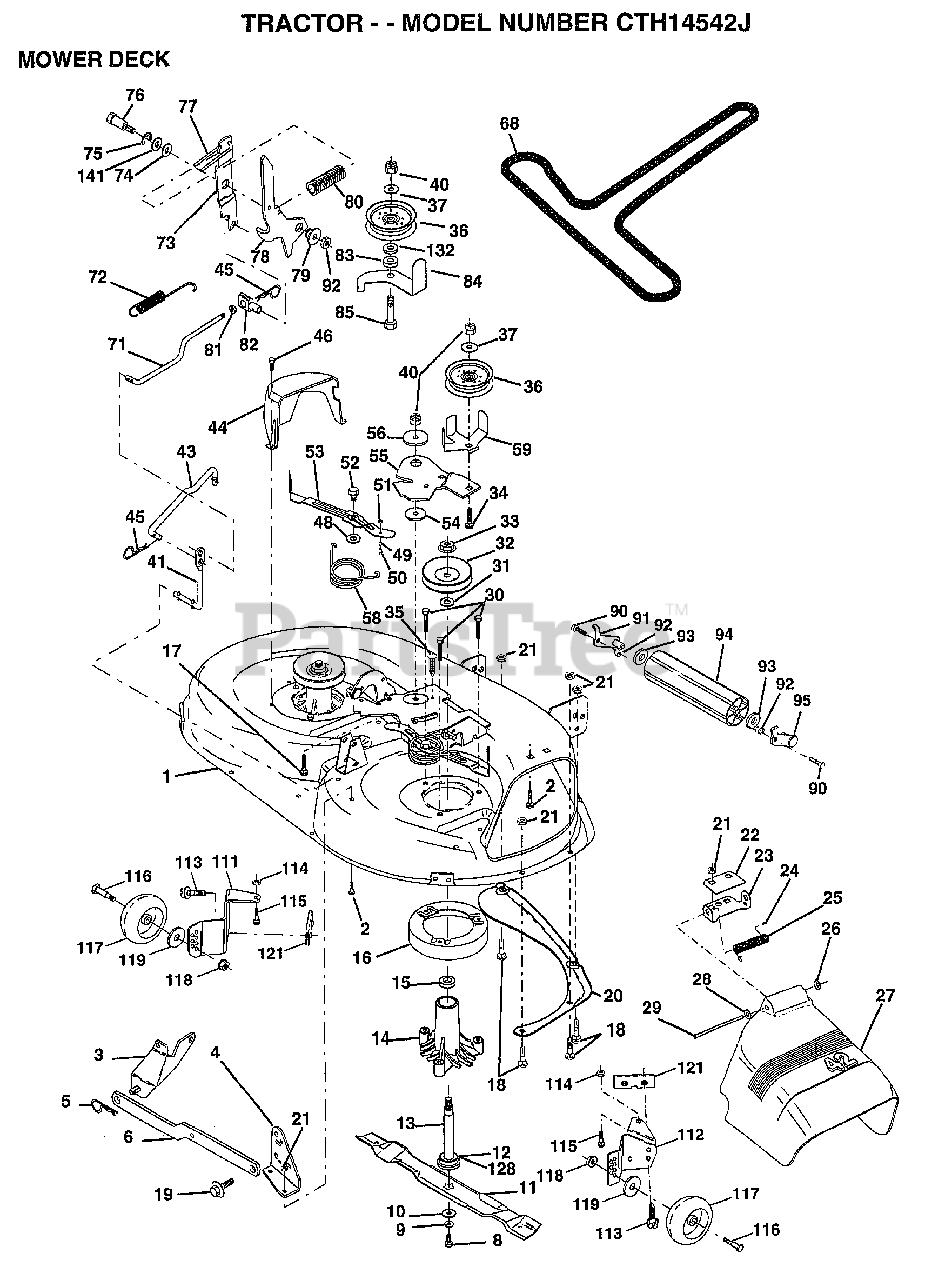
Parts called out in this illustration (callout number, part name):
1	"HOUSING ASSY.42"""
2	BOLT
3	BRKT ASM SWAY BAR
4	BRKT DECK SW BAR
8	BLADE BOLT
10	WASHER.HARD.BLADE
11	"BLADE.42"" HIPERF"
12	BEARING.BALL
14	HSG ASM MANDREL
15	BEARING
16	STRIPPER RND MWR
17	BOLT RDHD 3/8-16
18	BOLT
19	BOLT SHD 5/16-18
20	BAFFLE VORTEX 42
22	STIFFENER BRKT
23	DEFLECTOR BRKT
24	CAP-SLEEVE LT
25	SPRING TORSION
26	NUT PUSH M
27	DEFLECTOR.SHIELD
28	WASHER
29	HINGE ROD
30	"SCREW-THD ROLL,WA"
31	WASHER
32	PULLEY.MANDREL.42
34	BOLT
35	XMAS TREE FASTNER
36	FLAT IDLER PULLEY
37	WASHER
41	PIVOT ROD
43	ROD CLUTCH W/NIBS
44	GUARD MAND LH BLK
45	RETAINER M
46	SCREW.1/4-20X5/8
48	HARD SMALL WASHER
49	ROLLER ASM-CAM
50	SHOULDER BOLT
51	LOCKNUT
52	BOLT.SHLD.5/16-18
53	BRAKE PAD ARM ASM
54	HARDENED WASHER
55	ARM-IDLER
56	SPACER RETAINER
58	SPRING TORSN BRAK
59	GUARD IDLER TUV
68	BELT.V.T-PATH
71	ROD CLUTCH 38/42
72	SPRING.EXT.RETURN
73	CLUTCH ARM SECOND
74	WASHER
75	RING
76	SHOULDER BOLT
77	SPRING KEEPER
78	ARM CLUTCH PRIMARY
79	BUSHING
80	SPRING.CLUTCH.MWR
81	NUT
82	TRUNION ADJ
83	WASHER
84	"KEEPER-BELT,FIXED"
85	BOLT
90	BOLT
92	NUT
93	WASHER
111	BRACKET.GWHL.LH.
112	BRACKET.GWHL.RH.
113	SCREW
116	BOLT M
117	WHEEL.GUAGE
118	LOCKNUT
119	WASHER
121	BRACKET.EXTRD.GWL
128	WASHER.FELT.
132	WASHER GT
141	WASHER .T
